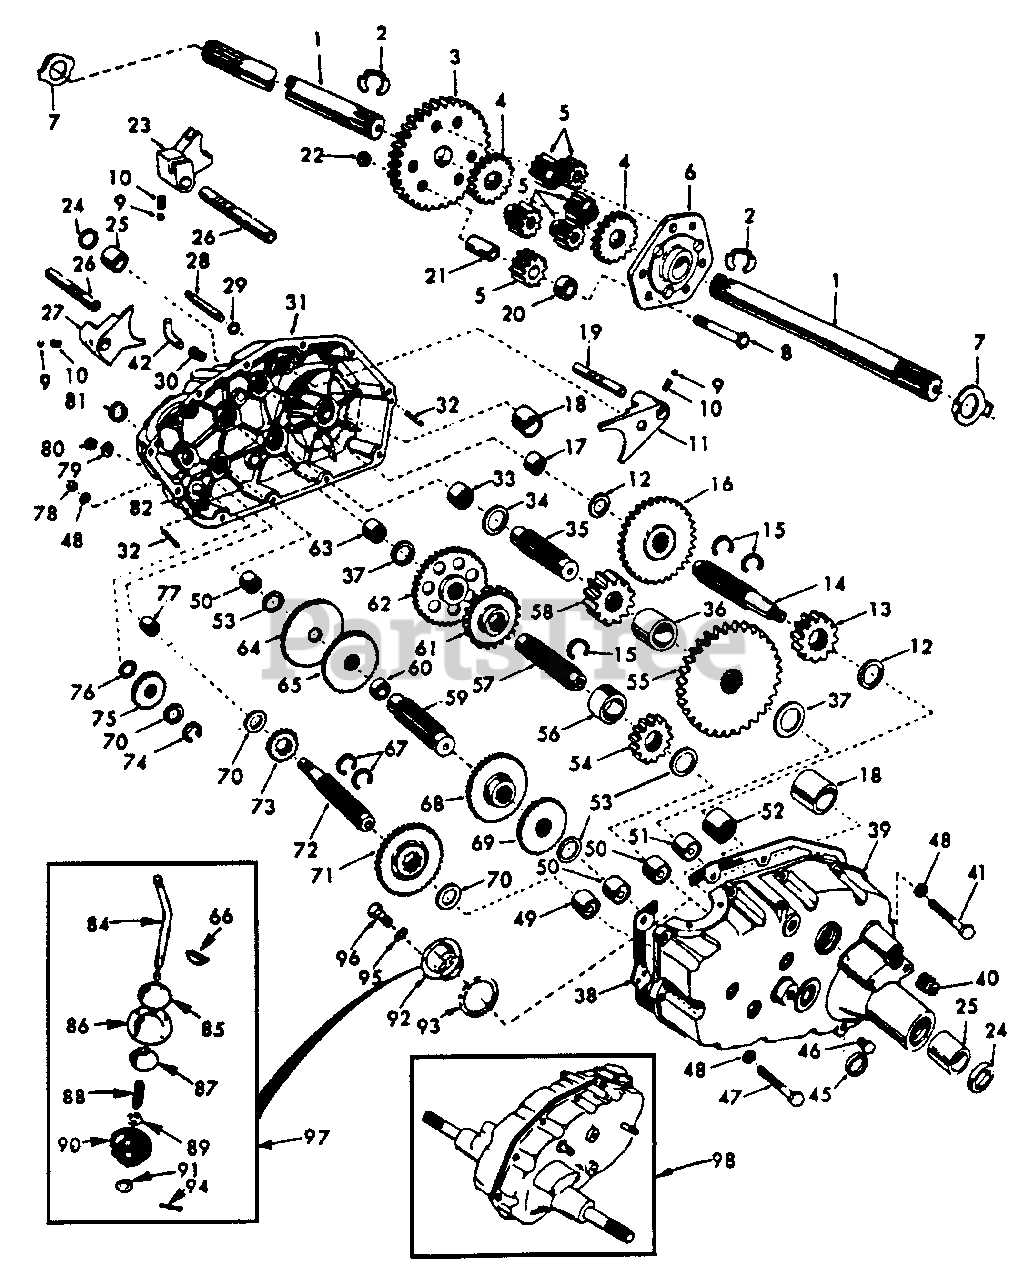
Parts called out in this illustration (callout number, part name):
1	Axle Shaft
2	Retaining Ring
3	Final Drive Gear
4	Differential Gear
5	Differential Pinion
6	Differential Carrier
7	Axle Thrust Washer
8	Bolt, Hex 3/8-24 x 3-1/4 (1" Thread Length)
9	Steel Ball
10	Spring Shift Fork Detent
11	Spring Shift Fork, High-Low Range
12	Thrust Bearing Race
13	4th Reduction Pinion
14	3rd Reduction Gear Shaft
15	Snap Ring, Crescent Type
16	High-Low Range Gears
17	Needle Bearing
18	Sintered Iron Bearing
19	Shift Fork Shaft, High-Low Range
20	Differential Pinion Spacer
21	Differential Pinion Bushing
22	Gripco Centerlock Nut 3/8-24
23	Shift Fork, LH
24	Oil Seal
25	Sintered Iron Bearing
26	Shift Fork Shaft
27	Shift Fork, RH
28	Shift Shaft, High-Low Range
29	Oil Seal
30	Pressure Relief Valve
31	Gearcase, Reverse Idler Shaft and Bearings, RH
32	Dowel Pin
33	Needle Bearing
34	Thrust Bearing Race
35	4th Reduction Gear Shaft
36	4th Reduction Gear Spacer
37	Thrust Bearing Race
38	Gearcase Gasket
39	Gearcase and Bearings, LH
40	Pipe Plug 1/2-14 N.P.T.
41	Bolt, Hex 5/16-18 UNC x 1-5/8
42	Elbow, Street, 900
45	Oil Seal
46	Pipe Plug 1/4-18 N.P.T.
47	Bolt, Hex 5/16-18 x 1-1/2 Grade 5
48	Washer, Lock, Hvy Helical 5/16
49	Needle Bearing
50	Needle Bearing
51	Needle Bearing
52	Needle Bearing
53	Thrust Bearing Race
54	3rd Reduction Pinion, Low
55	4th Reduction Gear
56	3rd Reduction Pinion Spacer
57	2nd Reduction Gear Shaft
58	Final Drive Pinion
59	1 st Reduction Gear Shaft
60	1st Reduction Shaft Spacer
61	3rd Reduction Pinion High
62	2nd Reduction Gear
63	Needle Bearing
64	Low Speed Gear and 2nd Reduction Pinion Cluster
65	Reverse Gear
66	Key, Hi-Pro 1/8 x 17/32
67	Snap Ring, Crescent Type
68	Intermediate Speed Gear
69	High Speed Gear
70	Thrust Bearing Race
71	Intermediate and High Speed Cluster Pinions
72	Input Shaft
73	Low Speed Pinion
75	Reverse Idler Gear
76	Reverse Idler Thrust Washer
77	Needle Bearing
78	Nut, Hex 5/16-18
79	Sealing Washer
80	Nut, Hex, Jam 7/16-20
81	Oil Seal
82	Reverse Idler Shaft
84	Gear Shift Lever, Bent
85	Gear Shift Cap
86	Gear Shift Ball Cover and Pin
87	Shift Lever Guide Ball, Keyed
88	Spring
89	Washer 15/32 x 15/16 x 16 Gauge
90	Shift Mechanism Seal
91	Washer 9/16 x 15/16 x 12 Gauge
92	Gear Shift Gate and Reinforcement
93	Shift Ball Cover Gasket
94	Cotter Pin 1/8 x 3/4
95	Washer, Lock 5/16
96	Bolt, Hex 5/16-18 UNC x 7/8
97	Gear Shift Lever Assembly
98	Transaxle Assembly
